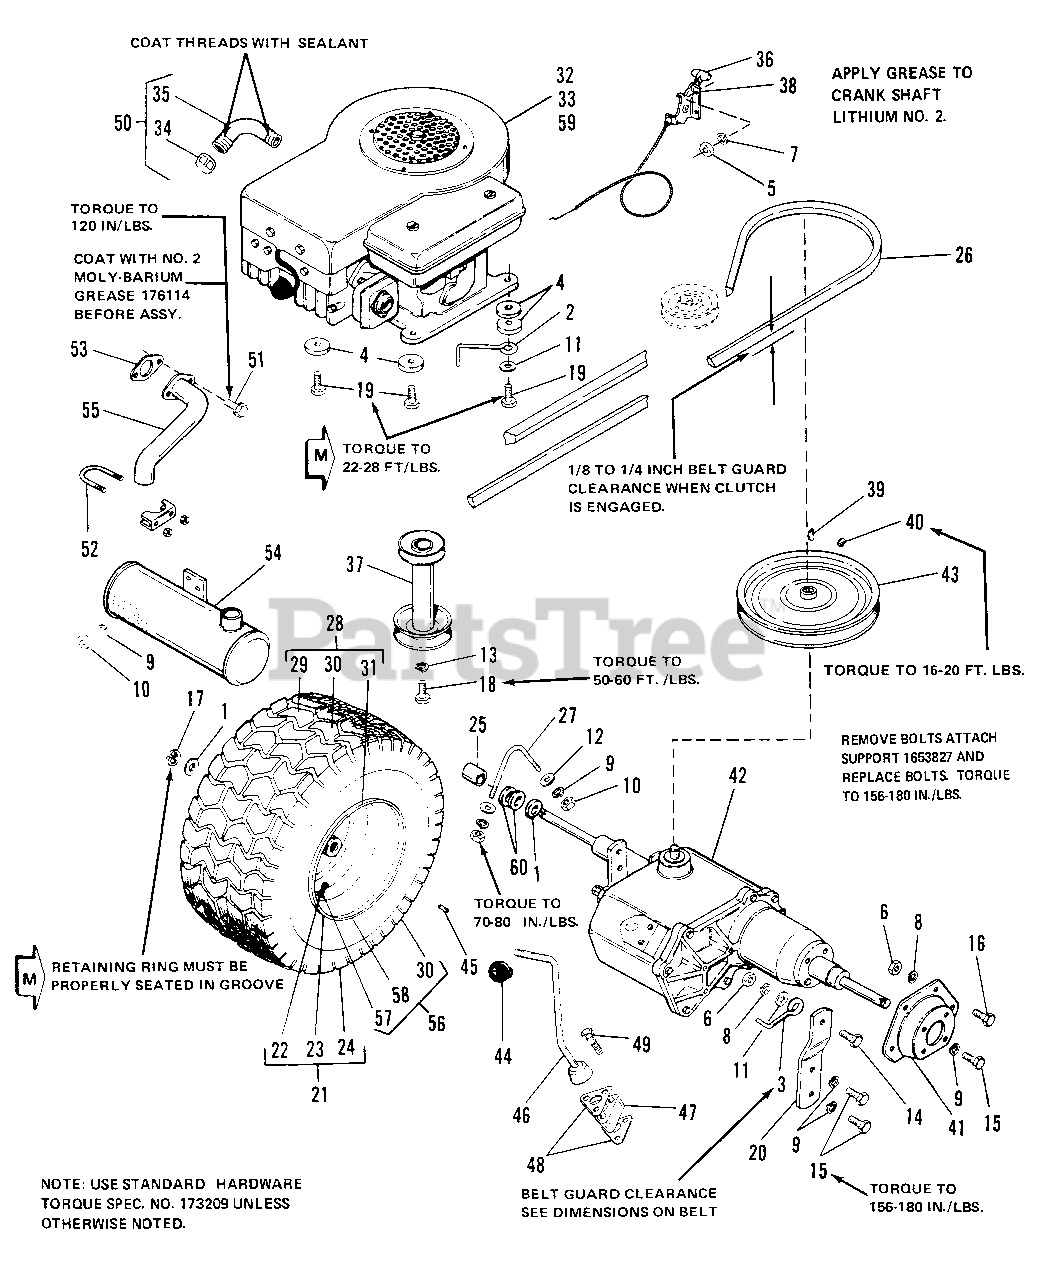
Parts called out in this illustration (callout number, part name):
5	NUT, Hex, 1/4-20
6	NUT, Hex, 3/8-16
7	LOCKWASHER, Spring, 1/4
8	LOCKWASHER, Spring, 3/8
9	LOCKWASHER, Spring, 5/16
10	NUT, Hex, 5/16-18
11	WASHER, Plain, 3/8
12	WASHER, Plain, 5/16
13	LOCKWASHER, Spring, 7/16
14	CAPSCREW, Hex Hd., 3/8-16 x 1-1/4 Gr. 5
15	CAPSCREW, Hex Hd., 5/16-18 x 1 Gr. 5
16	CAPSCREW,HexHd., 3/8-16 x 3/4 Gr. 5
17	KLIPRING, .75 Dia Shaft
18	CAPSCREW, Hex Hd., 7/16-20 x 1-1/4, Gr. 8
19	SCREW, Taptite, Washer Hd., 3/8-16 x 1-3/4
20	SUPPORT, Strap
21	WHEEL & TIRE ASSY, 18 x 6-1/2-8 (4108 Manual Start Only)
22	VALVE STEM & CAP (Used on 4108 ES & MS)
23	WHEEL ASSY (4108 Manual Start Only)
24	* TIRE, 18 x 6-1/2-8 (4108 Manual Start Only)
26	V-BELT, Arbor Drive, 50"
27	BOLT, Axle
28	WHEEL & TIRE ASSY, 18 x 8-1/2-8 (4108 Electric Start Only)
29	* TIRE, 18 x 8-1/2-8 (4108 Electric Start Only)(Goodyear)
30	WHEEL (4018 Electric Start & 4111 Only)
31	* TIRE, 18 x 8-1/2-8 (4108 Electric Start Only)(Carlisle)
32	ENGINE ASSY, 8 HP, Briggs & Stratton (Electric Start Synchro-Balanced)
33	ENGINE, 8 HP, Briggs & Stratton, Model 252707, Type 0130-01 (Manual Start Synchro-Balanced)
34	PIPE, Cap, 3/8
35	OIL DRAIN PIPE
36	KNOB
37	PULLEY ASSY, Engine
38	CONTROL ASSY
39	KEY, Woodruff, No. 61, 3/16 x 5/8
40	SCREW, Set, 5/16-18 x 1/2
41	SUPPORT, L.H.
42	TRANSMISSION, Peerless
45	KEY, 3/16 x 3/16 x 1-1/2
46	LEVER, Shift
47	BLOCK, Riser
48	GASKET
50	OIL DRAIN PIPE & CAP SUB-ASSY
51	SCREW, Whiz-Lock, 5/16-18 x 3/4 (4111 Only)
52	CLAMPASSY, Exhaust (4111 Only)
53	GASKET, Muffler (4111 Only)
54	MUFFLER (4111 Only)
55	PIPE, Exhaust (4111 Only)
56	WHEEL & TlRE ASSY, 18 x 9-1/2-8 (4111 Only)
57	VALVE (4111 Only)
58	* TIRE 18 x 9-1/2-8 (4111 Only)
59	ENGINE, 11 HP, Briggs & Stratton, Model 191702, Type 5626-01, Syncro Bal.
60	WASHER Special
